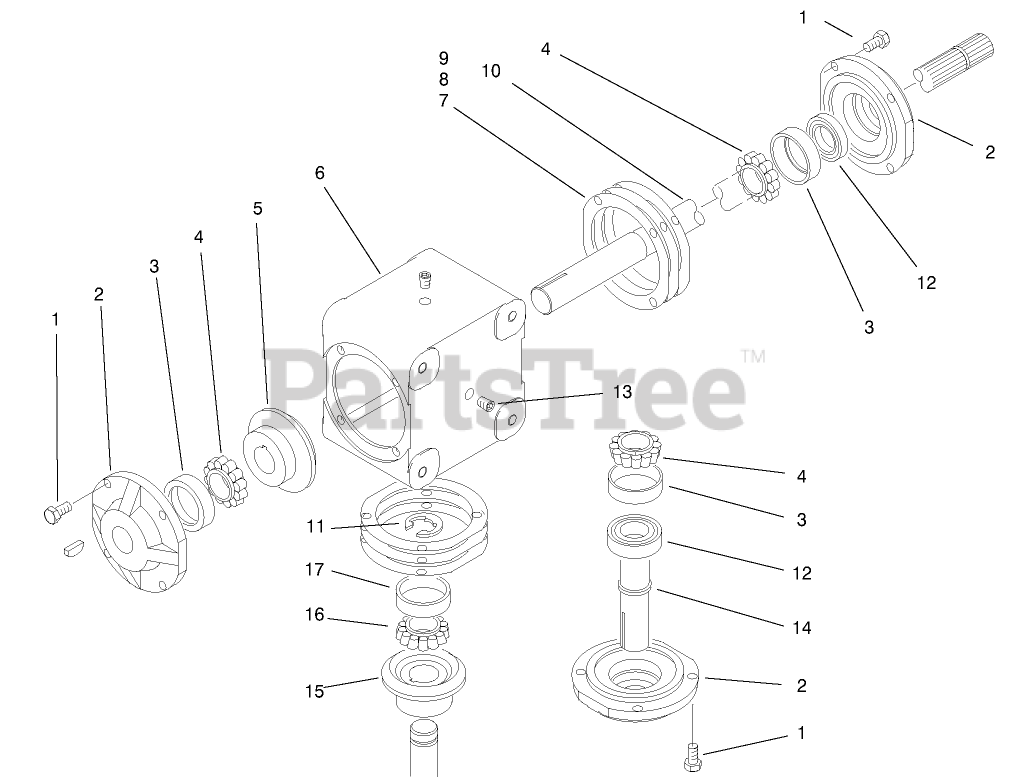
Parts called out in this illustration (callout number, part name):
1	SCREW
2	Cap
3	Cup
4	BEARING - CONE
5	GEAR LH
6	HOUSING
7	GASKET
8	GASKET
9	GASKET
10	SHAFT
11	Ring-Retaining
12	Seal
13	PLUG (OBS, C/R TO 281-10)
14	INPUT SHAFT
15	GEAR RH
16	Cone
17	Bearing Cup
